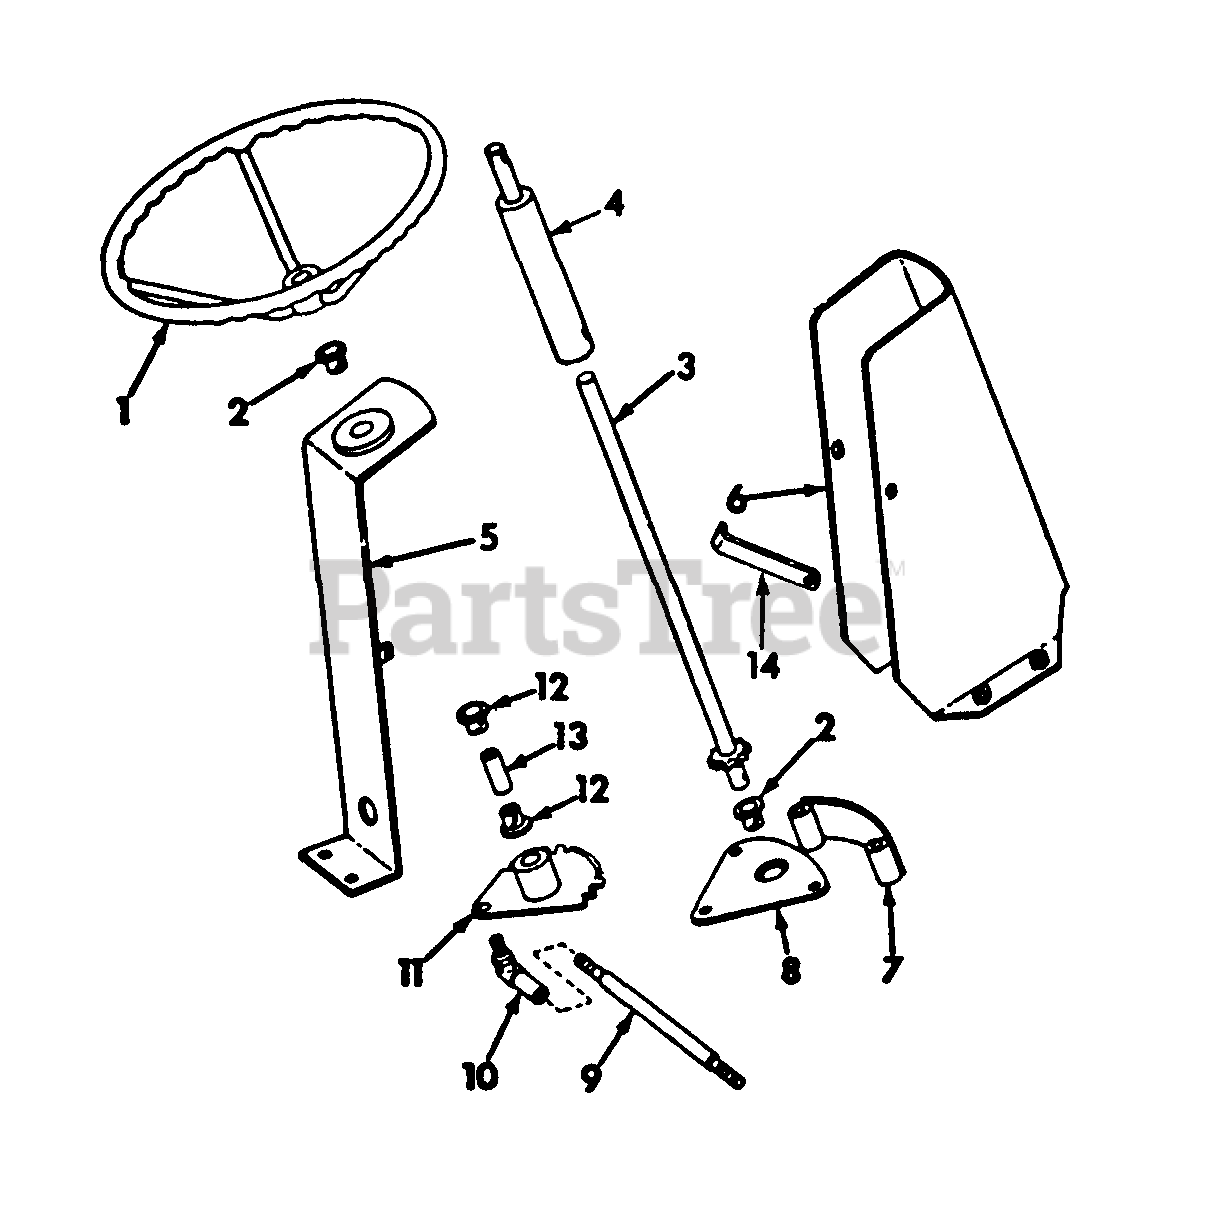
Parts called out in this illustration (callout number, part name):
1	WHEEL, STEERING
2	BEARING, STEERING SHAFT
3	SHAFT ASSY, LOWER STEERING
4	SHAFT, UPPER STEERING
5	SUPPORT ASSY, STEERING
6	SHROUD ASSY, STEERING SUPPORT
7	COVER, FRT STEERING GEAR
8	COVER ASSY, STEERING GEAR
9	STUD, DRAG LINK ROD
10	JOINT, 3/8-24 BALL
11	GEAR ASSY STEERING DRAG LINK
12	BEARING, STEERING GEAR
13	BUSHING, STEERING GEAR DRAG LINK
